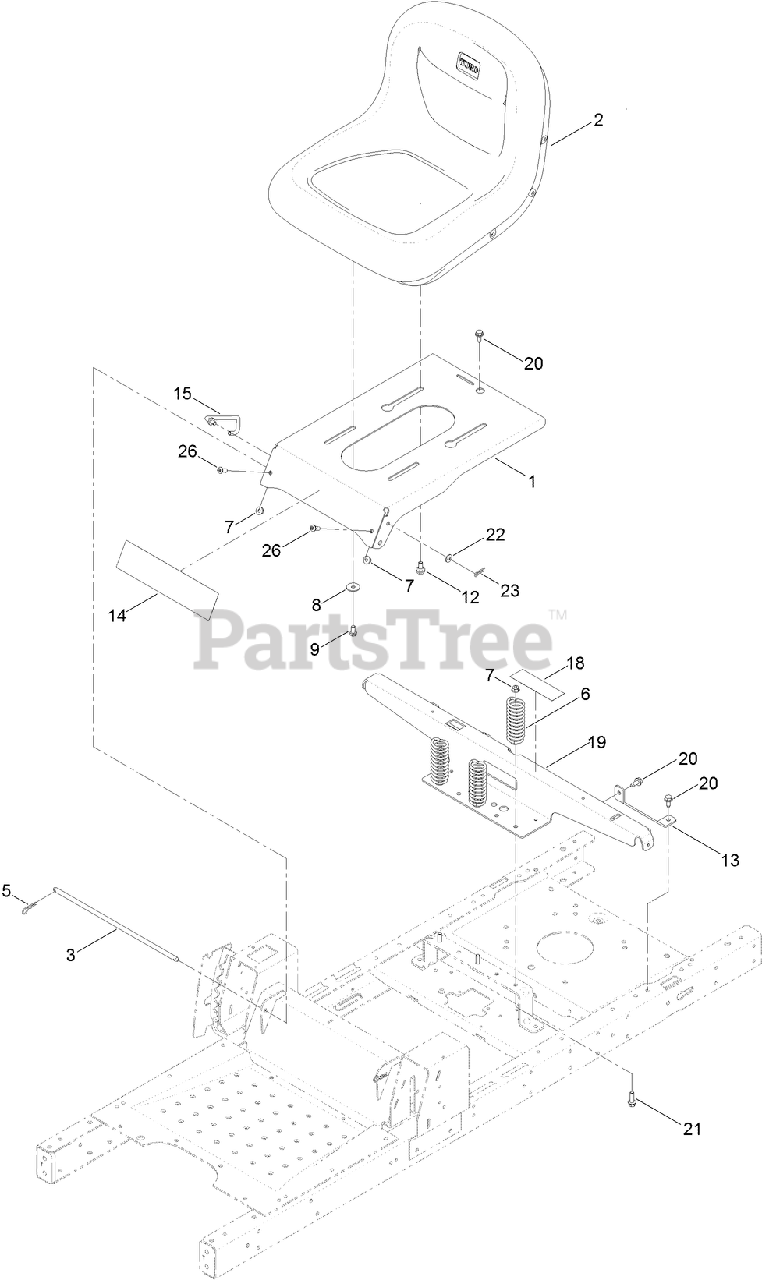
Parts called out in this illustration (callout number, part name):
1	PAN-SEAT
2	SEAT-15 INCH
3	ROD-PIVOT, NARROW
5	PIN-COTTER
6	SPRING-COMPRESSION
7	NUT-HF, NI
8	WASHER-PIVOT
9	SCREW-HH
12	BOLT-SHOULDER,HFH
13	SUPPORT-TANK, REAR
14	DECAL-TIMECUTTER
15	STOP-SEAT
18	DECAL-SERVICE, CE
19	SUPPORT-POD
20	SCREW-HWHTF
21	SCREW-HHF
22	WASHER-PLAIN
26	SCREW-HSBH
